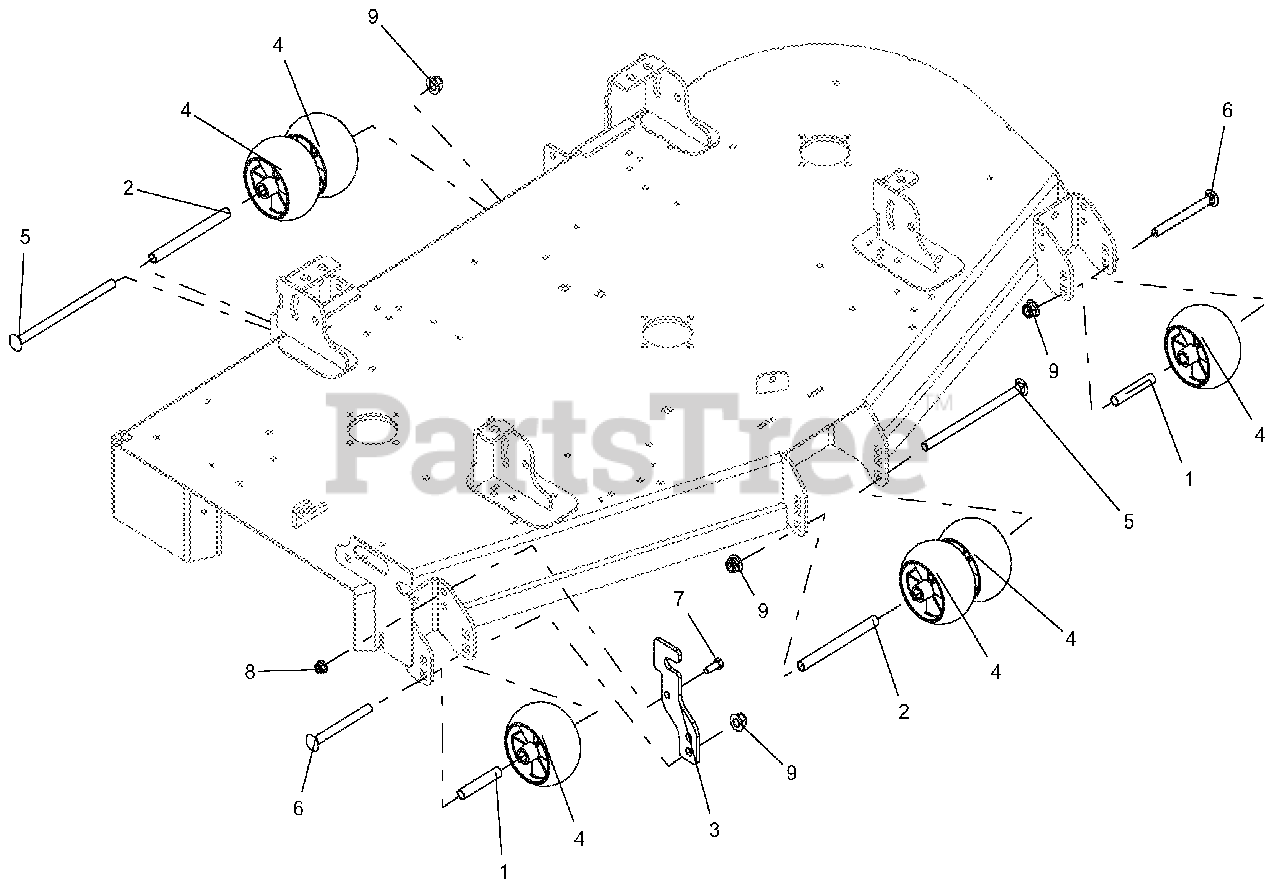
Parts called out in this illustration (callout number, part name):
1	SPACER, .510X.625X3.35
2	SPACER, .510 X .625 X 6.50
3	CHUTE STORAGE BRACKET-RED
4	ANTI-SCALP WHEEL - 5X3 CTR
5	BLT-RDHDSQNK .50-13X8Y.50
6	BLT-RDHDSQNK .50-13X5.00 G5 YWZC
7	BLT-HEX .38-16X1.00 GR5 YWZC
8	NUT-LK-NYL-FLG .38-16 YWZC
9	NUT-LK-NYL-FLG .50-13 YWZC
